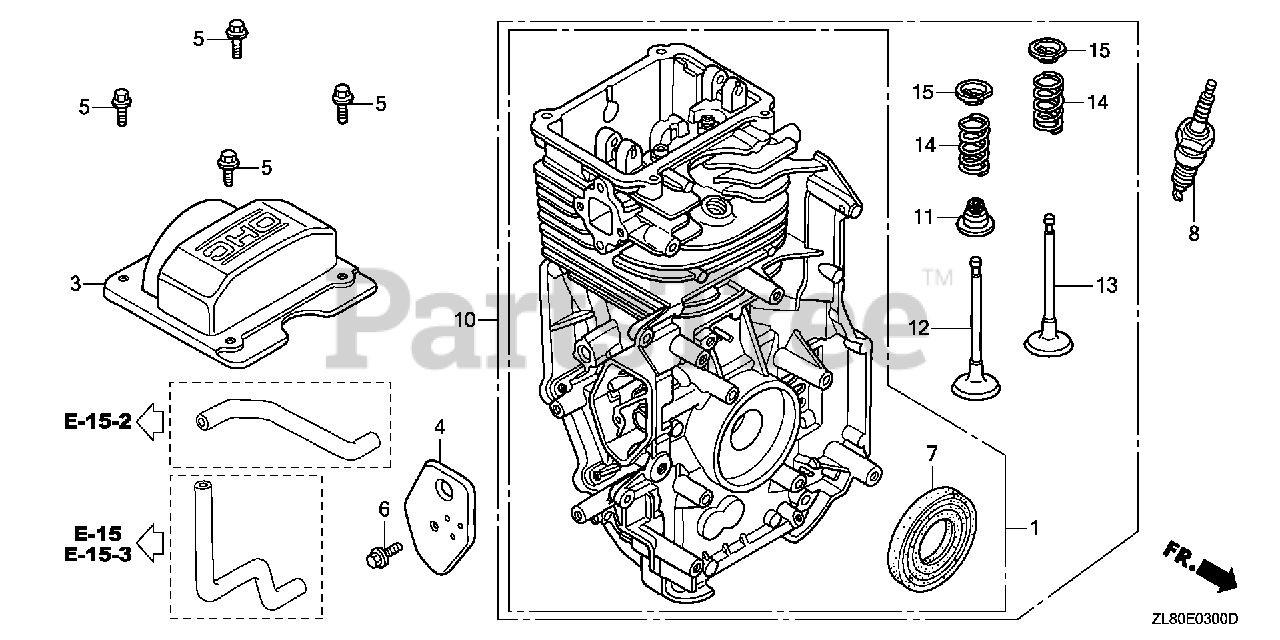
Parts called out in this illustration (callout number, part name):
1	CYLINDER ASSY.
3	COVER, CYLINDER HEAD
4	COVER, BREATHER (BREATHER VALVE ASSY.)
5	BOLT, FLANGE (6X12) (CT200)
6	BOLT, FLANGE (6X14) (CT200)
7	OIL SEAL (25.4X62X6)
8	SPARK PLUG (BPR6ES) (NGK)
11	SEAL, VALVE STEM
12	VALVE, IN. (ROCKNEL)
12	VALVE, IN.
13	VALVE, EX. (L8E)
13	VALVE, EX. (C8E)
14	SPRING, VALVE
15	RETAINER, VALVE SPRING
